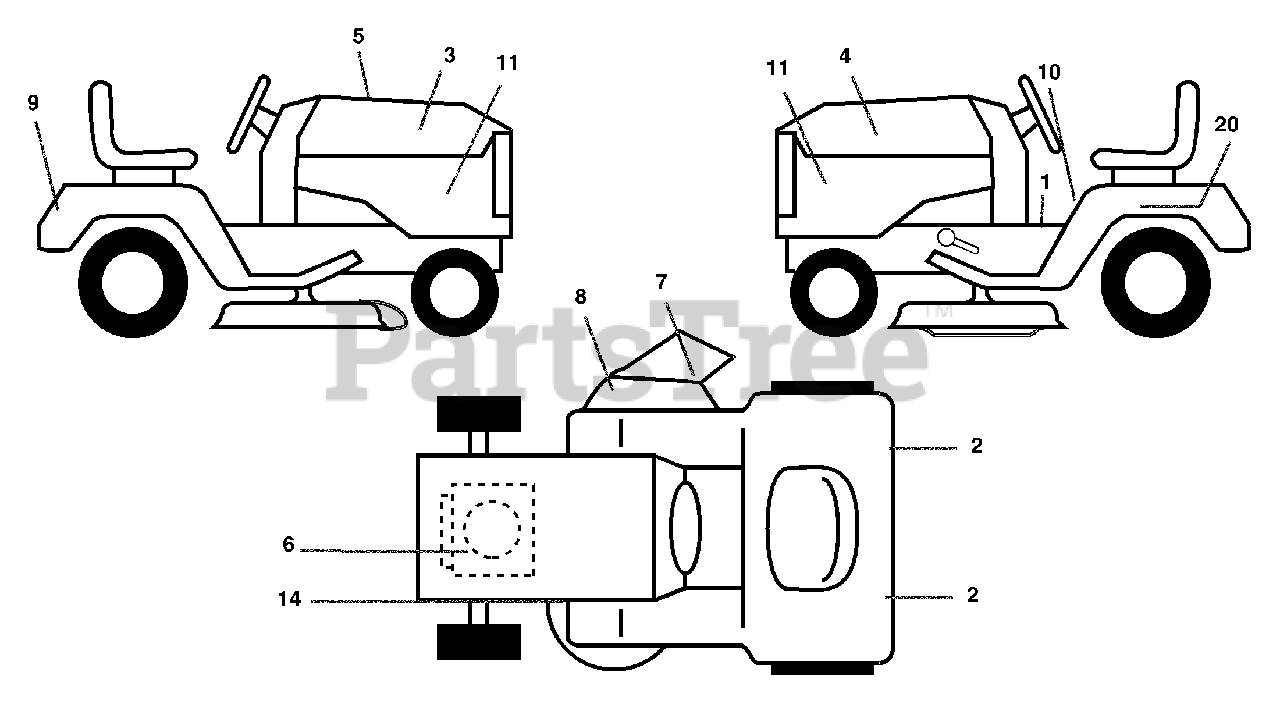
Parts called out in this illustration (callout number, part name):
1	Decal Oper. Step Thru Eng/Fr
2	Reflector Tail Light Red/Amber
3	Decal Hood RH
4	Decal Hood LH
5	Decal Hood Cust.
6	Decal Engine
7	Decal Deck B 42
8	Decal Warning
9	Decal Fender Husq
10	Decal Fender Danger Eng/Fr
11	Decal Side Panel
14	Decal V-Belt Schematic
20	Decal Bat Dan/Psn
